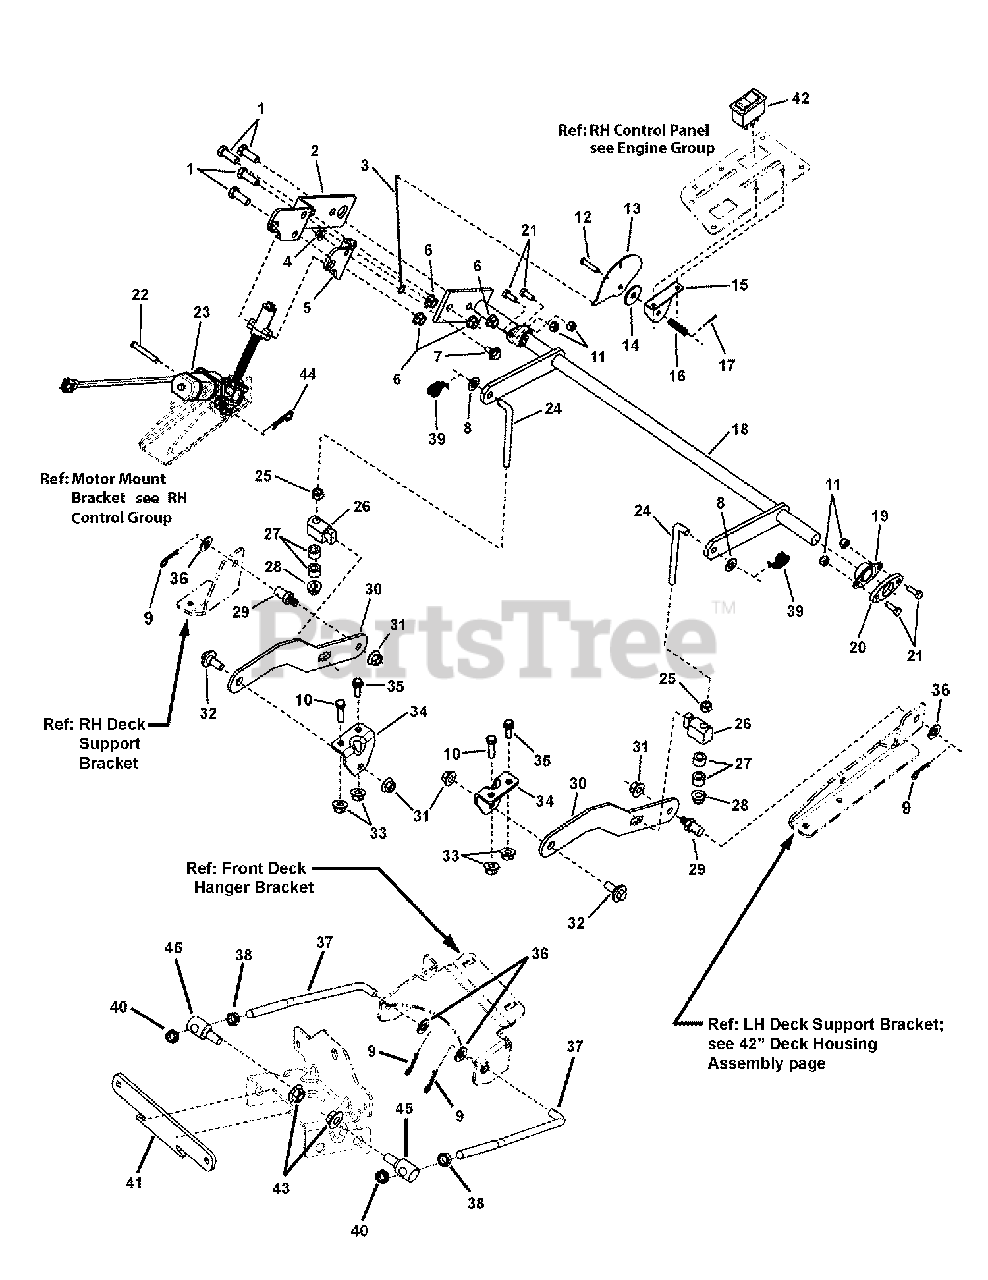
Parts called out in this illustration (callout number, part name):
1	SCREW, 3/8-16 x 1" Hex Head Cap, GR 5, YZ
2	BRACKET, Lift, Deck, Primary
3	ROD, Indicator, Height-Of-Cut
4	NUT, 1/4-20 Hex Flange Lock, GR 5, YZ
5	BRACKET, Lift, Deck, Secondary
6	NUT, 3/8-16 Hex Flange lock, YZ
7	SHOULDER BOLT, 1/4-20 x 3/8"
8	WASHER, 3/8" Flat (SAE)
9	HAIR PIN, 3/32 x 1-1/2" YZ
10	SCREW, 5/16-18 x 1" Hex Head Cap, GR 5, YZ
11	NUT, 1/4-20 Hex Center Lock, GR 5
12	CLEVIS PIN, .25 x 1.09
13	LEVER, Indicator, Height-Of-Cut
14	WASHER, 5/16" Nylon
15	BRACKET, Indicator, Height-Of-Cut
16	SPRING, Compression
17	COTTER PIN, .06 x 1/2", YZ
18	WELDMENT, Deck Lift, 38/42
19	BEARING, Flange, .75 ID PM
20	SPACER, Bearing, .25"
21	SCREW, 1/4-20 x 3/4" Hex Head Cap, GR 5 YZ
22	SHEAR PIN, .248 ID x 1-3/4" Long
23	MOTOR, Actuator, Lift, Deck
24	ROD, Mower Lift (3/8-16 thread) Yellow
25	NUT, 3/8-16 Hex, Black
26	TRUNNION, Powdered Metal, Yellow, Regent
27	SPACER, .385 ID x .6697 OD x .455 Long, PM YEL
28	NUT, 3/8-16 Hex Flange Esna, Black
29	PIN, 3/8-16 Threaded Shoulder
30	BAR, Rear Lift
31	NUT, 3/8-16 Hex Flange Center Lock, Zinc Plated
32	SHOULDER BOLT, 3/8-16 x .94, BZ
33	NUT, 5/16-18 Flange Lock, YZ
34	BRACKET, Deck Hanger
35	BOLT, 5/16-18 x 5/8" Hex Flange lock, GR 5, YZ
36	WASHER, 1/2" Flat (0.51 ID x 1.00 OD x .10 Thick) Black
37	ROD, Front Bail (1/2-13 thread) 46, 52" MWR
38	NUT, 1/2-13 Hex Jam, Black
39	COTTER PIN, Self Locking, 3/8, YZ
40	NUT, 1/2-13 Jam, Esna Light Thin
41	SUPPORT, Hanger (46/52)
42	SWITCH, Rocker Electric Height-Of-Cut
43	NUT, 1/2-13 Hex Flange Two-Way Lock Black
44	HAIRPIN, Quick, .080 Wire
45	TRUNNION, Unthreaded
